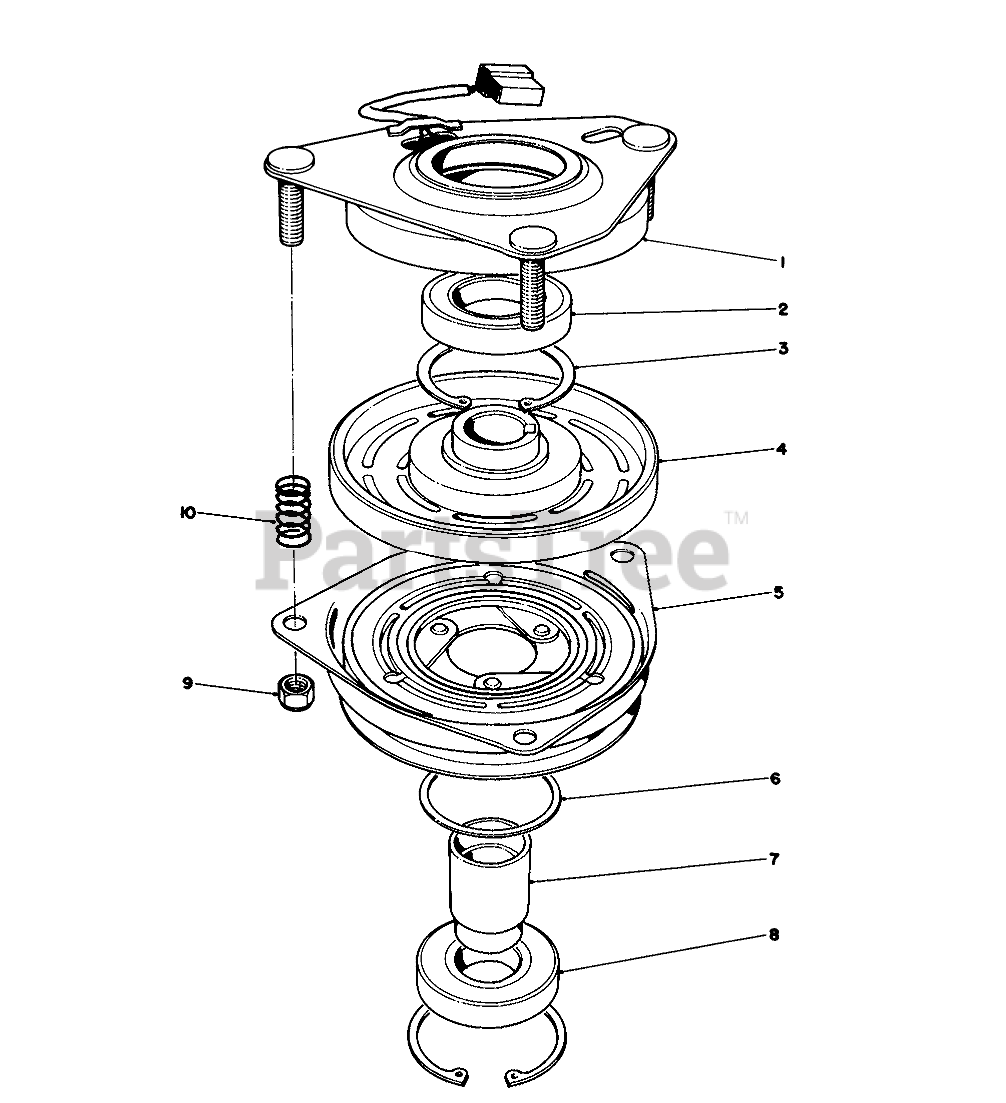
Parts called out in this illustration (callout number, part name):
1	Field Assy (Incl. Ref. #2 & 3)
2	BEARING-FIELD
3	RING-RETAINING
4	Field Coil, Rotor & Bearing Assy (Incl. Ref. #1)
5	Armature & Pulley Assy (Incl. Ref. #3, 6, 7 & 8)
6	SPACER-BEARING, PULLEY
7	COLLAR-BEARING
8	BEARING-PULLEY
9	NUT-HEX
10	SPRING
